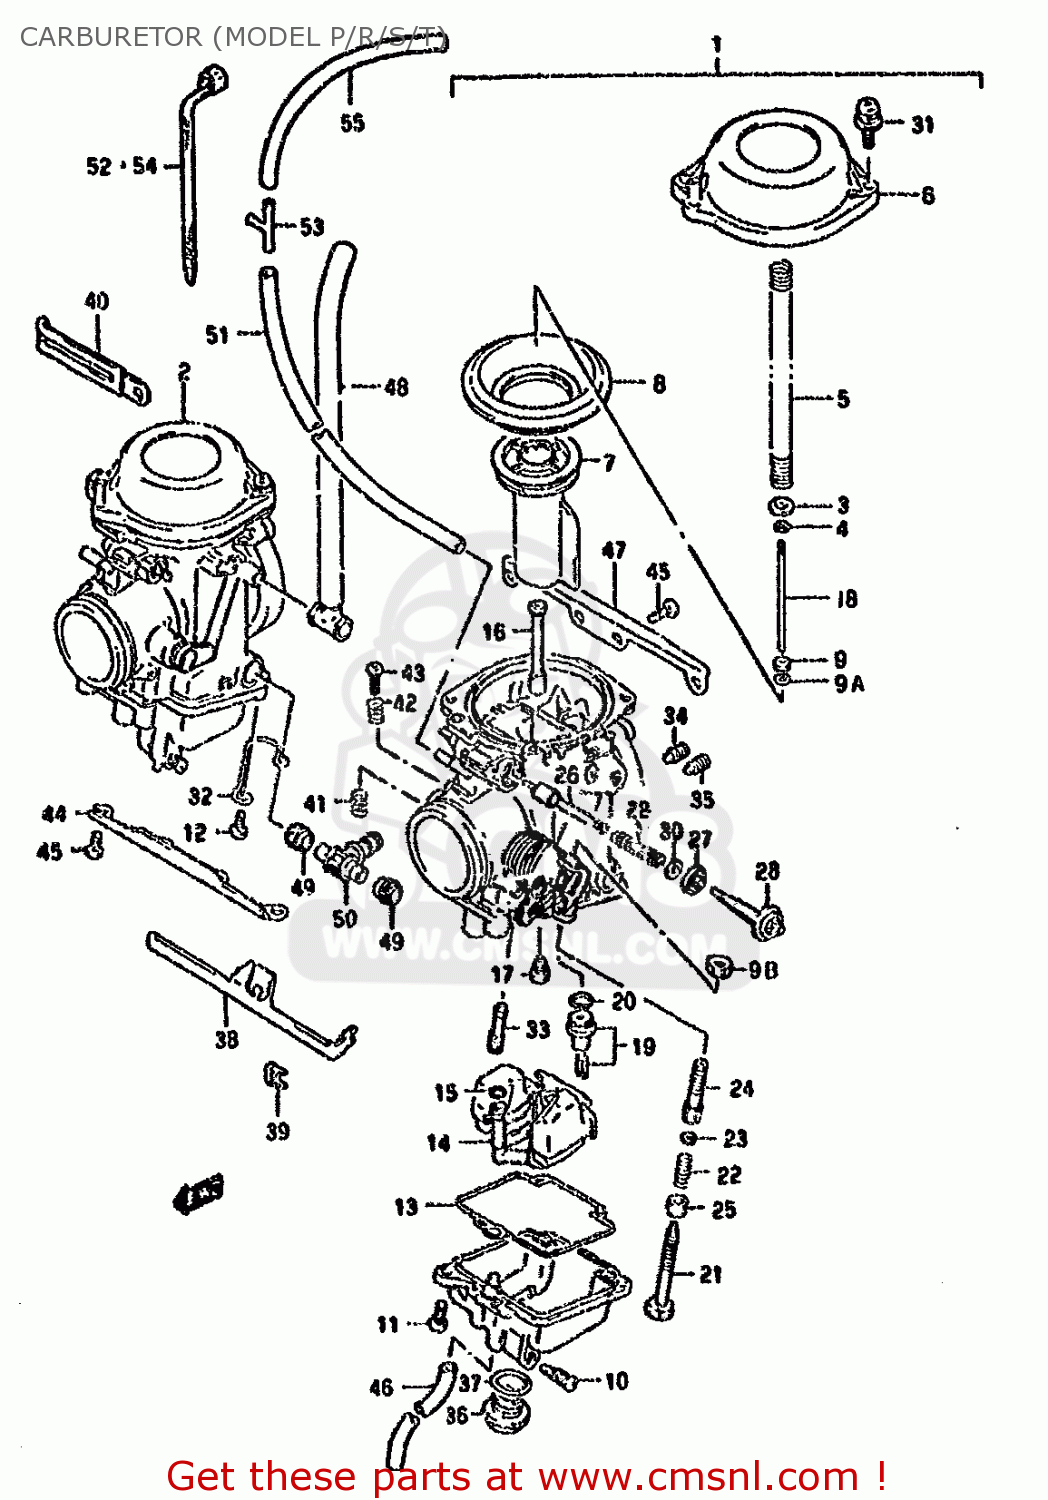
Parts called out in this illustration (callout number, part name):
1	CARBURETOR ASSY,LH
2	CARBURETOR ASSY,RH
3	RING
4	CLIP
5	SPRING
6	COVER ASSY,DIAPHRAGM
7	VALVE PISTON
8	DIAPHRAGM
9	RING
9A	WASHER
9B	NUT
10	SCREW,DRAIN
11	SCREW
12	SCREW(5X14)
13	GASKET,FLOAT CHAMBER (NAS)
14	FLOAT ASSY
15	O RING
16	JET,NEEDLE (O-3)
17	JET,MAIN(130)
18	NEEDLE,JET
19	VALVE ASSY,NEEDLE
20	O-RING,NEEDLE VALVE
21	ADJUSTER
22	SPRING
23	WASHER,STARTER SHAFT
24	ADJUSTER
25	RING
26	PLUNGER ASSY
27	CAP,STARTER
28	HOLDER,GUIDE
29	SPRING
30	WASHER
31	SCREW
32	CLIP
33	JET,PILOT(45)
34	JET,AIR
35	JET,AIR(0.6)
36	SCREW,GUIDE
37	O RING,DRAIN PLUG
38	LEVER,STARTER
39	HOLDER
40	CLAMP(L:80)
41	SPRING,THROTTLE SCREW
42	SPRING
43	SCREW
44	PLATE
45	SCREW
46	HOSE
47	PLATE
48	HOSE
49	SEAL
50	NIPPLE
51	HOSE,VACUUM
52	CLAMP(L:95)
53	JOINT,3 WAY
54	CLAMP(L:125)
55	HOSE,VACUUM
